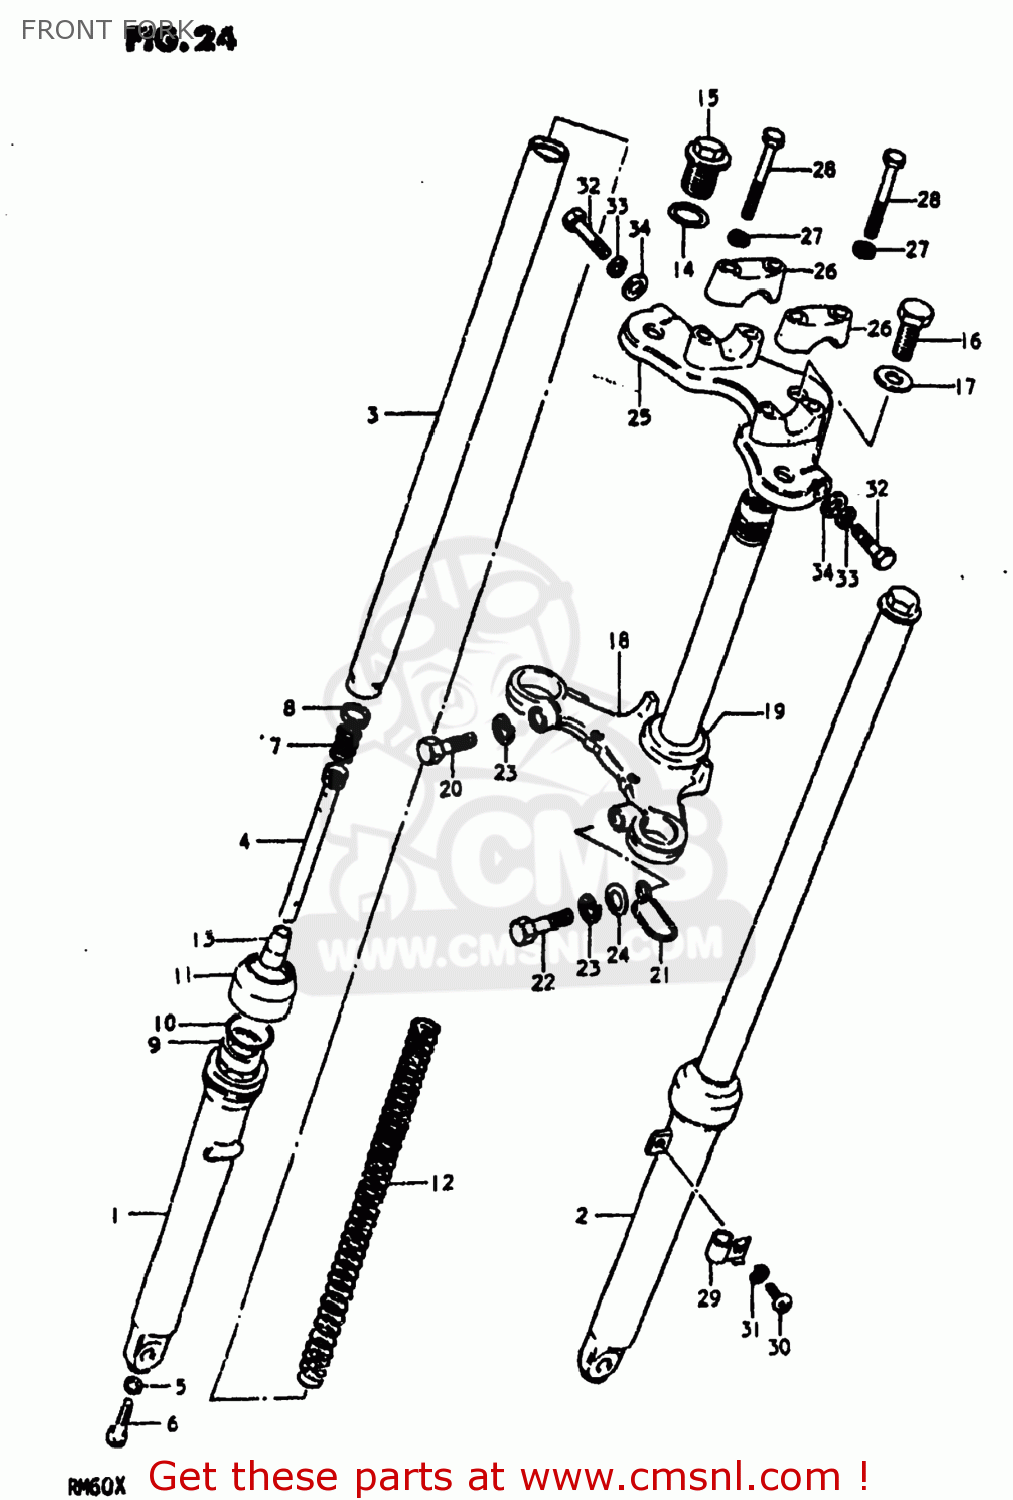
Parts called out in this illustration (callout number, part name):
1	TUBE,OUTER,RIGHT
2	TUBE,OUTER,LEFT
3	TUBE,FORK,INNER
4	CYLINDER,FRONT FORK
5	GASKET (NAS)
6	BOLT(8X27)
7	SPRING,REBOUND
8	RING,PISTON
9	OIL SEAL,FRONT FORK
10	CIRCLIP,FORK OIL SEAL
11	DUST SEAL
12	SPRING
13	PIECE,OIL LOCK
14	O-RING,FORK INNER TUBE
15	CAP,FORK
16	BOLT
17	WASHER(10.5X30X2.3)
18	STEM,STEERING
19	RACE,STEERING OUTER LWR
20	BOLT 10X30
21	CLAMP,METER CABLE
22	BOLT,M10X1.25X
23	LOCK WASHER
24	WASHER
25	HEAD,STEERING STEM
26	HOLDER,HANDLEBAR
27	LOCK WASHER
28	BOLT
29	CLIP,CABLE
30	SCREW
31	LOCK WASHER
32	BOLT 8X40
33	LOCK WASHER
34	WASHER
